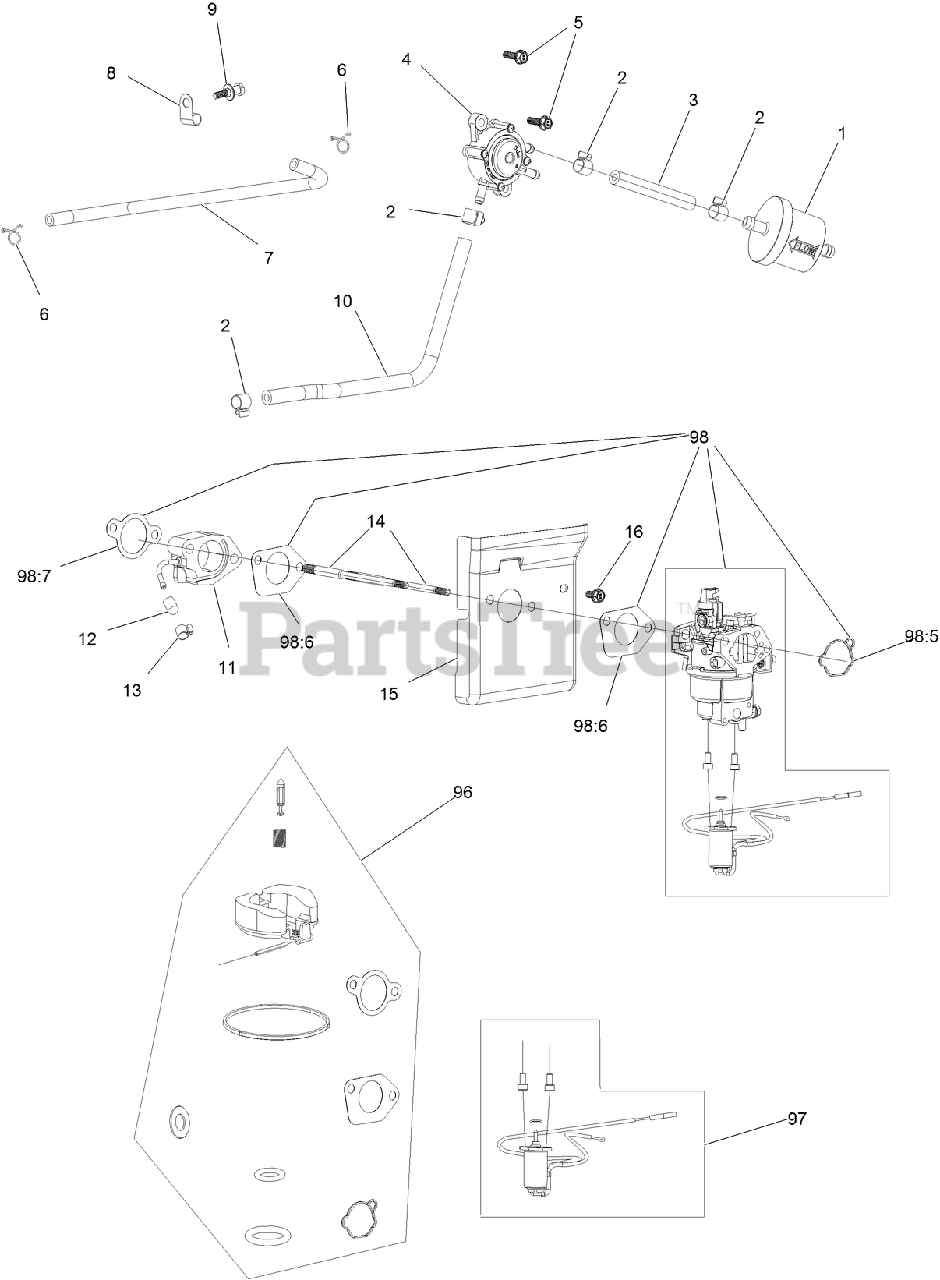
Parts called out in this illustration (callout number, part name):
1	FILTER-FUEL
2	CLAMP-FUEL LINE
3	LINE-FUEL
4	PUMP-PULSE, FUEL
5	SCREW-HHF
6	CLAMP-HOSE
7	LINE-PULSE
8	CLAMP-J
9	SCREW-SHOULDER, HH
10	LINE-FUEL
11	INSULATOR-CARBURETOR
12	CAP-SEAL
13	CLAMP-HOSE
14	STUD-MOUNT, CARBURETOR
15	SHROUD
16	SCREW-HHF
96	CARB REPAIR KIT WITH GASKETS
97	SOLENOID KIT
98:5	GASKET-CARBURETOR
98:6	GASKET-CARBURETOR
98:7	GASKET-CARBURETOR
